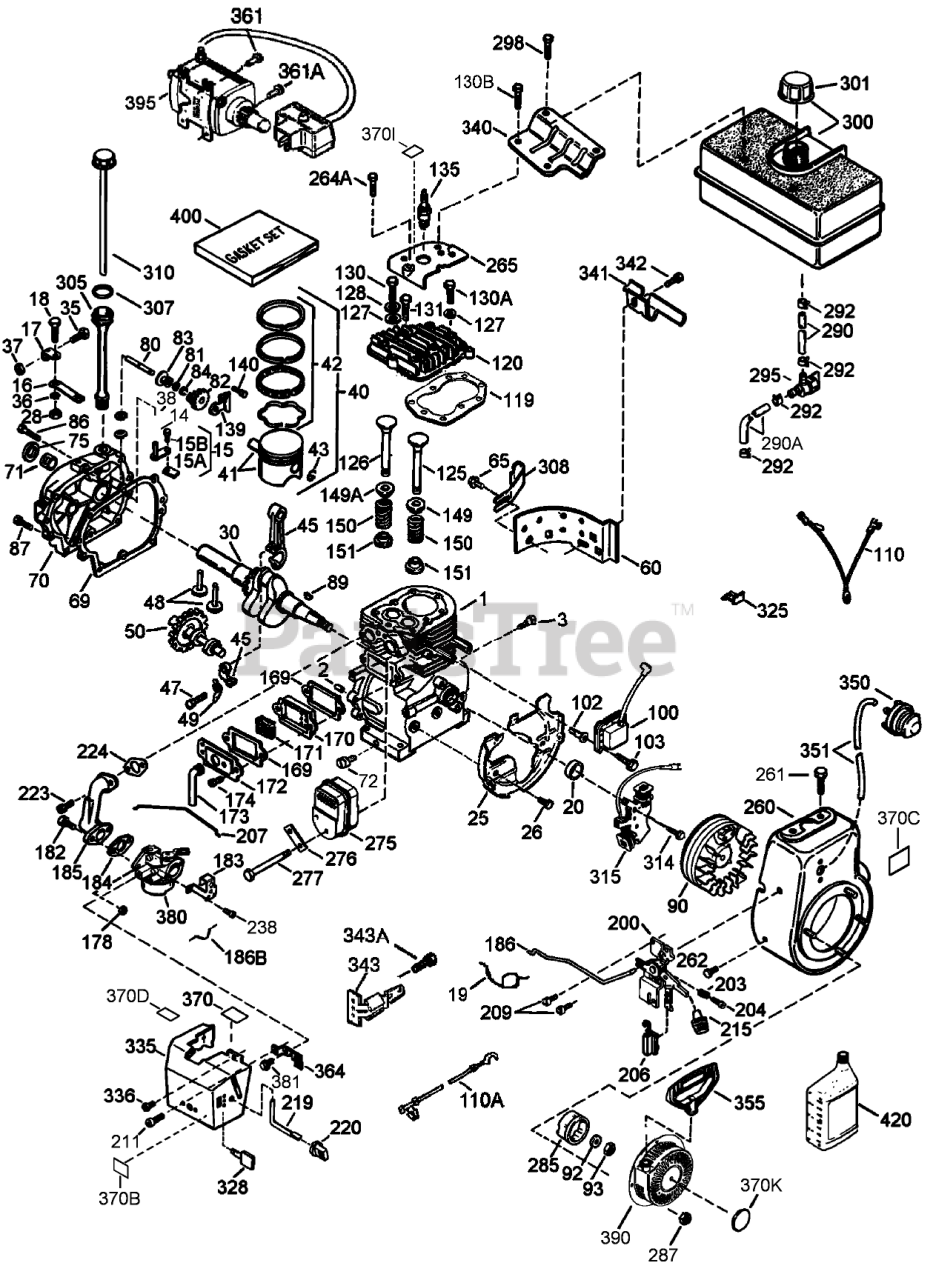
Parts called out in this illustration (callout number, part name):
1	Cylinder (Includes 2, 20, 72)
2	Pin-Dowel
3	Screw (1/4-20x1/2)
14	Washer-Flat
15	Governor Rod (Includes 15A, 15B)
15A	Yoke-Governor
15B	Screw (6-40x5/16)
16	Lever-Governor
17	Clamp-Lever, Governor
18	Screw (T-15, 8-32x7/16)
19	Spring-Throttle
20	Seal-Oil
25	Blower Housing Baffle
26	Screw (1/4-20x19/32)
28	Nut-Lock
30	Crankshaft
35	Screw
36	Washer-Lock
37	Nut-Lock
38	Ring-Retaining
40	Piston Pin and Ring ASM (STD)
40	Piston Pin and Ring ASM (.010)
41	Piston and Pin ASM (STD) (Includes 43)
41	Piston and Pin ASM (.010) (Includes 43)
42	Ring Set (STD)
42	Ring Set (.010)
43	Retaining Ring-Piston Pin
45	Connecting Rod ASM (Includes 47, 49)
47	Bolt-Rod, Connecting
48	Lifter-Valve
49	Dipper-Oil
50	Camshaft (MCR)
60	Extension-Housing, Blower
65	Screw
69	Gasket-Cover, Cylinder
70	Cylinder Cover (Includes 71, 75, 80-87)
71	Bushing-Crankshaft
72	Plug-Drain, Oil (SQH 1/4-18)
75	Seal-Oil
80	Shaft-Governor
81	Washer
82	Governor Gear ASM. (Includes 81)
83	Spool-Governor
84	Ring-Retaining
86	Screw (1/4-20x1-3/16)
87	Screw (1/4-20x1-11/16)
89	Key-Flywheel
90	Flywheel ASM
92	Washer-Belleville
93	Nut-Flywheel
100	Solid State Ignition (Includes 101)
102	Stud-Mounting, Solid State
103	Screw (T-15, 10-24 x 15/16)
110	Wire-Ground
110A	Wire-Ground
119	Gasket-Head, Cylinder
120	Head-Cylinder
125	Valve-Exhaust (STD) (Includes 151)
125	Valve-Exhaust (1/32 OS)
126	Intake Valve (Std) (Includes 151)
126	Valve-Intake (.03 O S)
127	Washer-Flat
128	Washer-Belleville
130	Screw (5/16-18x1-1/2)
130A	Screw (5/16-18x1-25/32)
130B	Screw (5/16-18x39/64)
131	Screw (5/16-18 X 2)
135	Spark Plug-Resistor (R J19 L M)
139	Bracket-Gear, Governor
140	Screw (10-24x1/2)
149	Cap-Spring, Valve
149A	Cap-Spring, Valve
150	Spring-Valve
151	Keeper-Spring, Valve
169	Gasket-Cover, Valve
170	Body-Breather
171	Element-Breather
172	Cover-Valve
173	Tube-Breather
174	Screw
178	Nut and Lock Washer (1/4-28)
182	Screw (1/4-28x1)
183	Bracket-Choke
184	Gasket-Carburetor To Intake Pipe
185	Pipe-Intake
186	Link-Governor
186B	Spring-Choke
200	Control Bracket (Includes 19, 203, 204)
